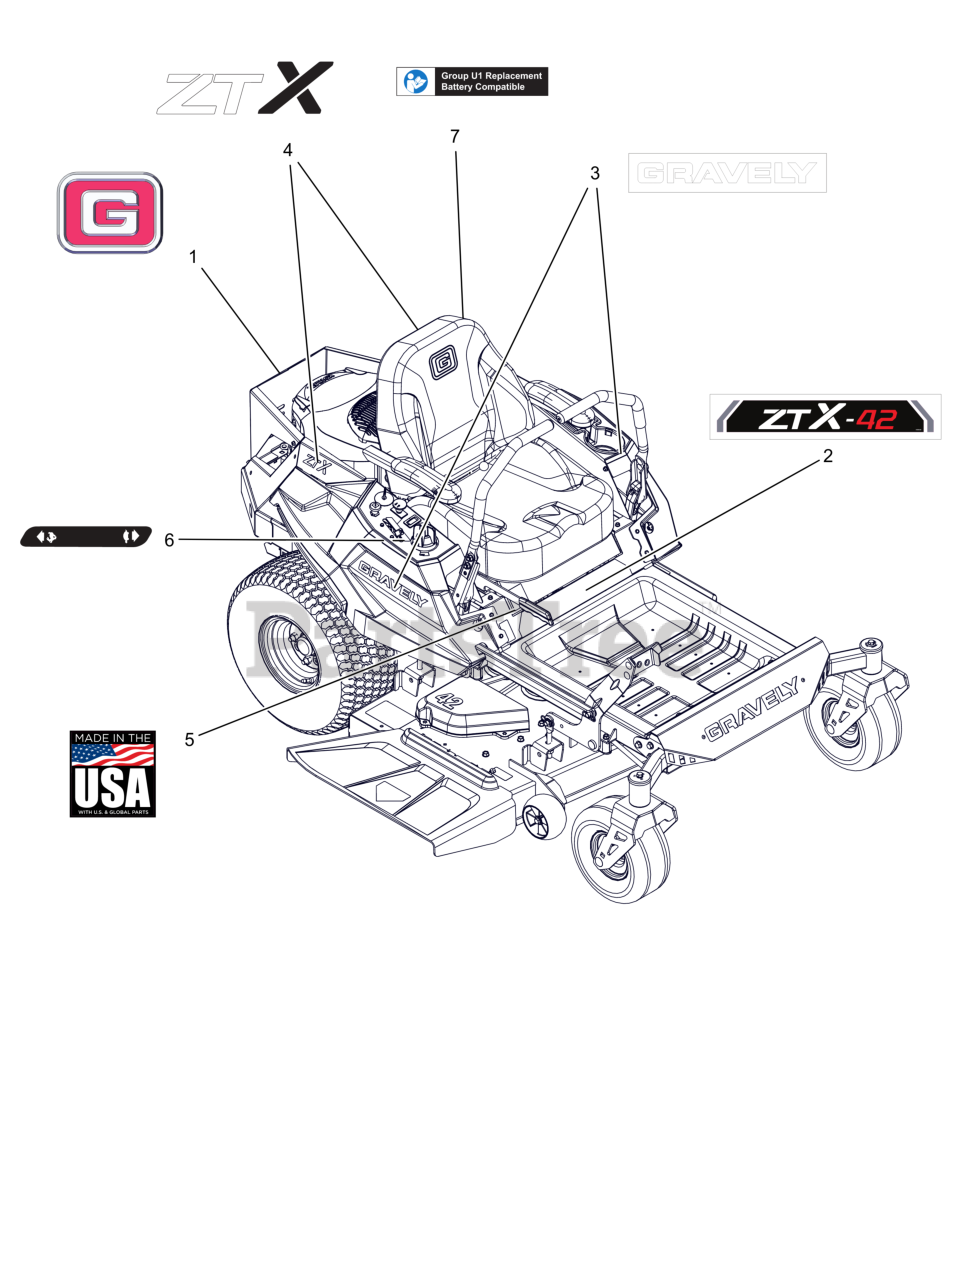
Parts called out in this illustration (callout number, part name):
1	DECAL, GRAVELY BRAND
2	DECAL, GRAVELY ZT X 42
3	DECAL, 9.5" GRAVELY LOGO
4	DECAL, REAR WRAP - ZTX
5	DECAL, MADE IN USA
6	DECAL, DASH DECAL
7	DECAL, U1 BATTERY REPLACEMENT
